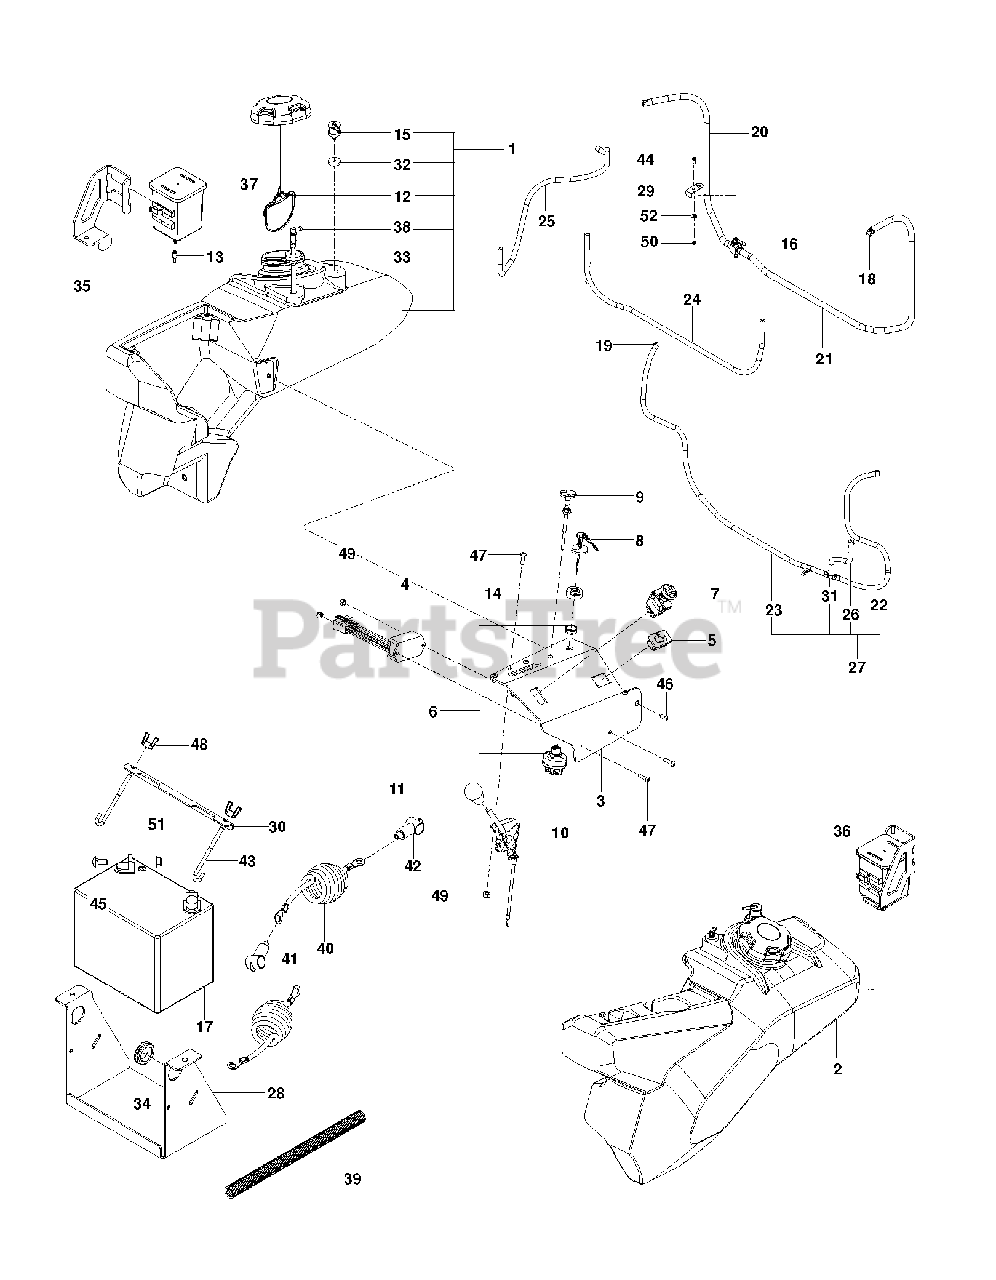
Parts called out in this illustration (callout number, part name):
1	RT FUEL TANK ASM EPA
2	LT FUEL TANK ASM EPA
3	PANEL.CONTROL.GAS.GRAY
4	TIMER, SEAT
5	RP GUAGE.SRVCMNDR.HRMTR.
6	SWITCH, IGNITION, INDAK
7	SWITCH, PTO 10 AMP
8	KEY, IGNITION
9	CABLE, CHOKE, 48"
10	CABLE, THROTTLE, 46"
11	KNOB - SHIFT
12	CAP, FUEL
13	CAP, VINYL
14	CAP IGNITION NUT
15	VALVE.FUEL.CHECK
16	FUEL VALVE
17	BATTERY, 12 V 330 AMP
18	HOSE CLAMP
19	CLAMP, HOSE
20	LINE, FUEL, 22"
21	LINE, FUEL, 38"
22	HOSE, 3/16" VAPOR, 21"
23	HOSE, VAPOR 3/16 X 39"
24	HOSE, VAPOR 3/16 X 30"
25	FUEL LINE 33"
26	HOSE, 3/16" VAPOR, 7-1/2"
27	ASSEMBLY, VAPOR LINE
28	BRACKET, BATTERY, BLK
29	BRACKET,FUEL VALVE, BLACK
30	BRACKET, BATTERY MOUNT
31	TEE, FUEL LINE 3/16"
32	GROMMET, CHECK VALVE
33	RUBBER GROMMET
34	RUBBER GROMMET
35	MOUNT, CANISATER, RT
36	MOUNT, CANISTER, LT
37	CANNISTER, CARBON
38	FITTING, FUEL
39	LOOM, SPLIT, CONVOLUTED
40	CABLE, POSITIVE, 55"
41	CABLE, NEG, 55"
44	HCS 1/4C X 3/4 HCS
45	BOLT 5/16C X 3/4" CARRIAGE
46	SCR #10-24 X 3/8 SKT HD BLK OX
47	SCR #10-24 X .75 SKT HD BLK
48	WING NUT 1/4
49	NUT 10-24 NYLOC
50	JAM NUT 1/4C (2 2 PW01)
51	5/16-18 NYLOC FLANGE NUT
52	WASHER 1/4 FLAT
